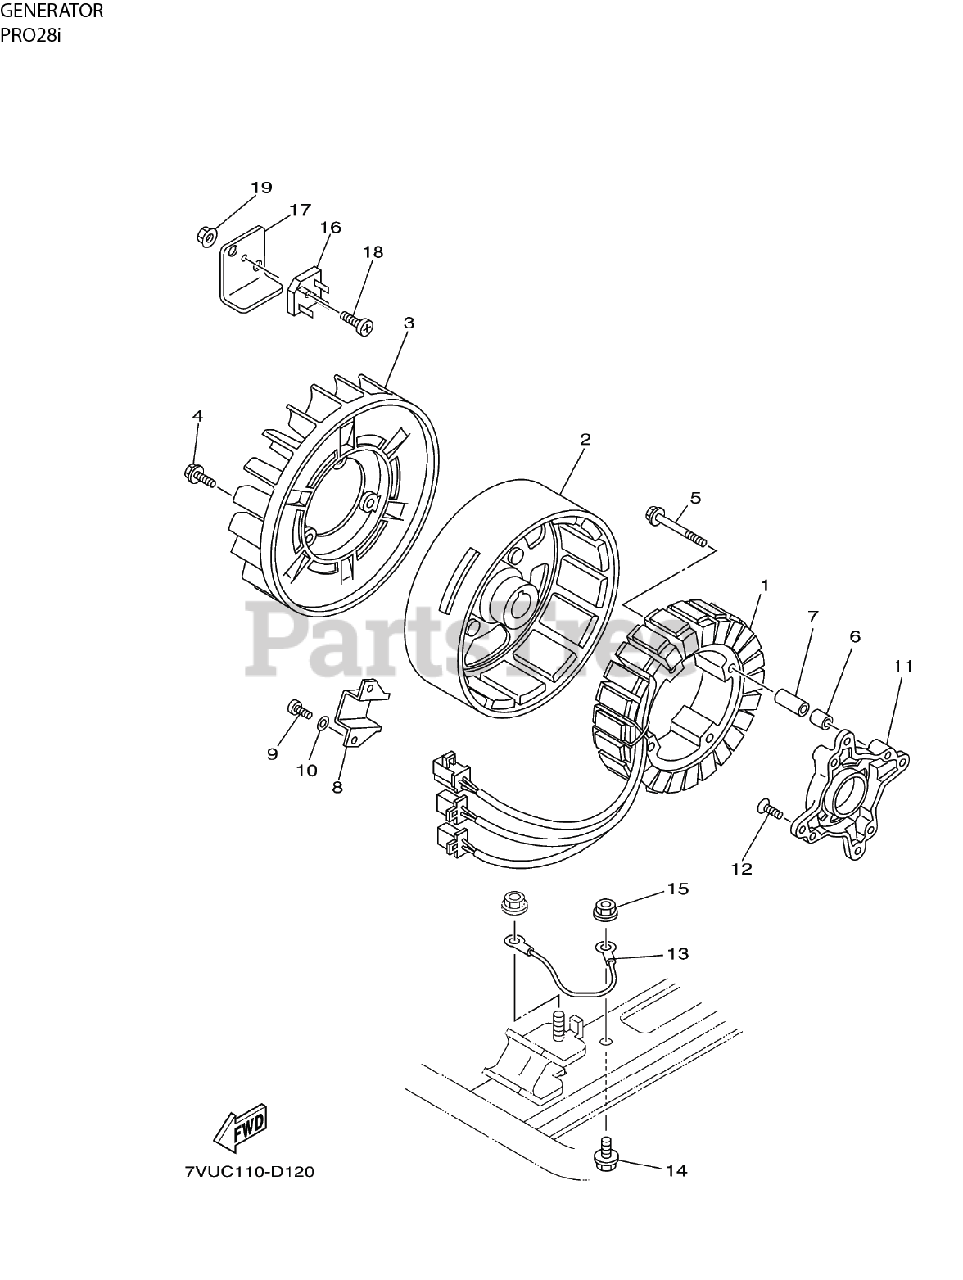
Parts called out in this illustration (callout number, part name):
1	STATOR ASSEMBLY
2	FLYWHEEL, ROTOR ASSEMBLY
3	FAN, GENERATOR
4	SCREW - BOLT FLANGE
5	SCREW - BOLT FLANGE
6	CRANKCASE 1
7	SPACER, TUBE
8	BRACKET, HARNESS
9	SCREW - PAN HEAD
10	WASHER, PLATE
11	ADAPTER - BRACKET, GENERATOR MOUNT
12	SCREW - FLAT HEAD
13	LEAD, WIRE ASSEMBLY
14	SCREW - BOLT FLANGE
16	RECTIFIER ASSEMBLY
17	PLATE, HEAT SINK
18	SCREW - BOLT FLANGE
19	NUT, U FLANGE
